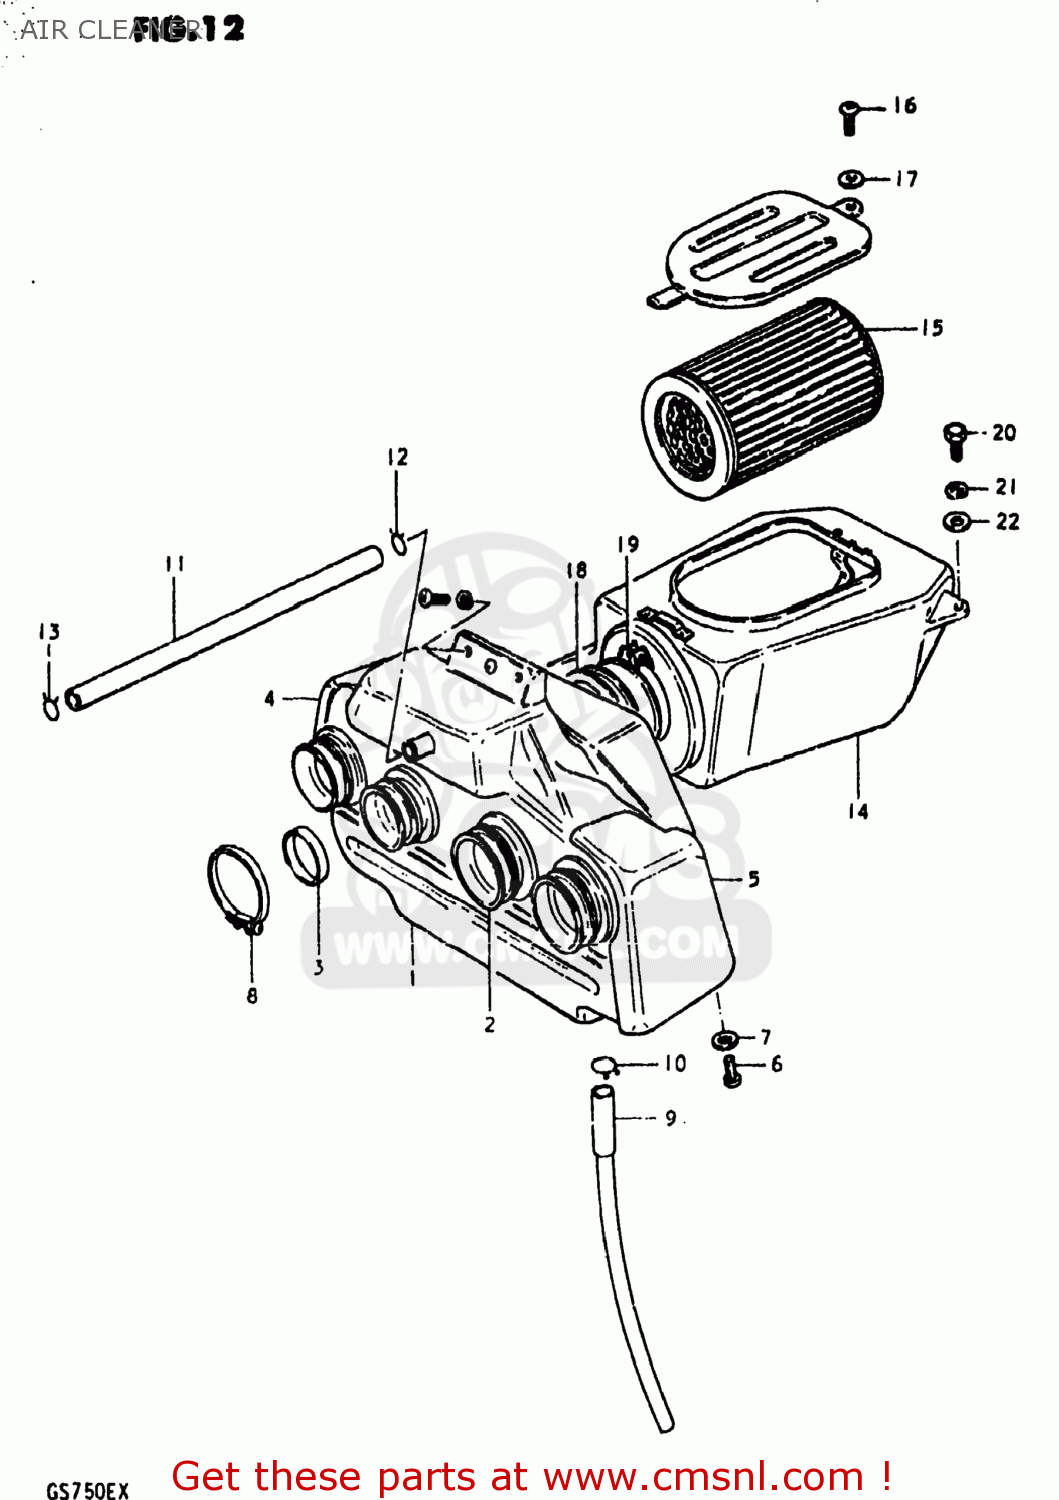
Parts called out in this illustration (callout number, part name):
1	CASE COMP,AIR CLEANER
2	TUBE,AIR CLEANER OUTLET
3	RING,CARBURETOR AIR IN
4	COVER,AIR CLEANER,RIGHT
5	COVER,AIR CLEANER,LEFT
6	SCREW
7	WASHER
8	CLAMP
9	DRAIN TUBE
10	CLIP
11	HOSE
12	CLIP,BREATHER HOSE
13	CLIP
14	CLEANER ASSEMBLY,AIR
15	FILTER,AIR CLEANER
16	SCREW
17	WASHER
18	JOINT,HOSE AIR CLEANER
19	CLAMP
20	BOLT
21	LOCK WASHER
22	WASHER
